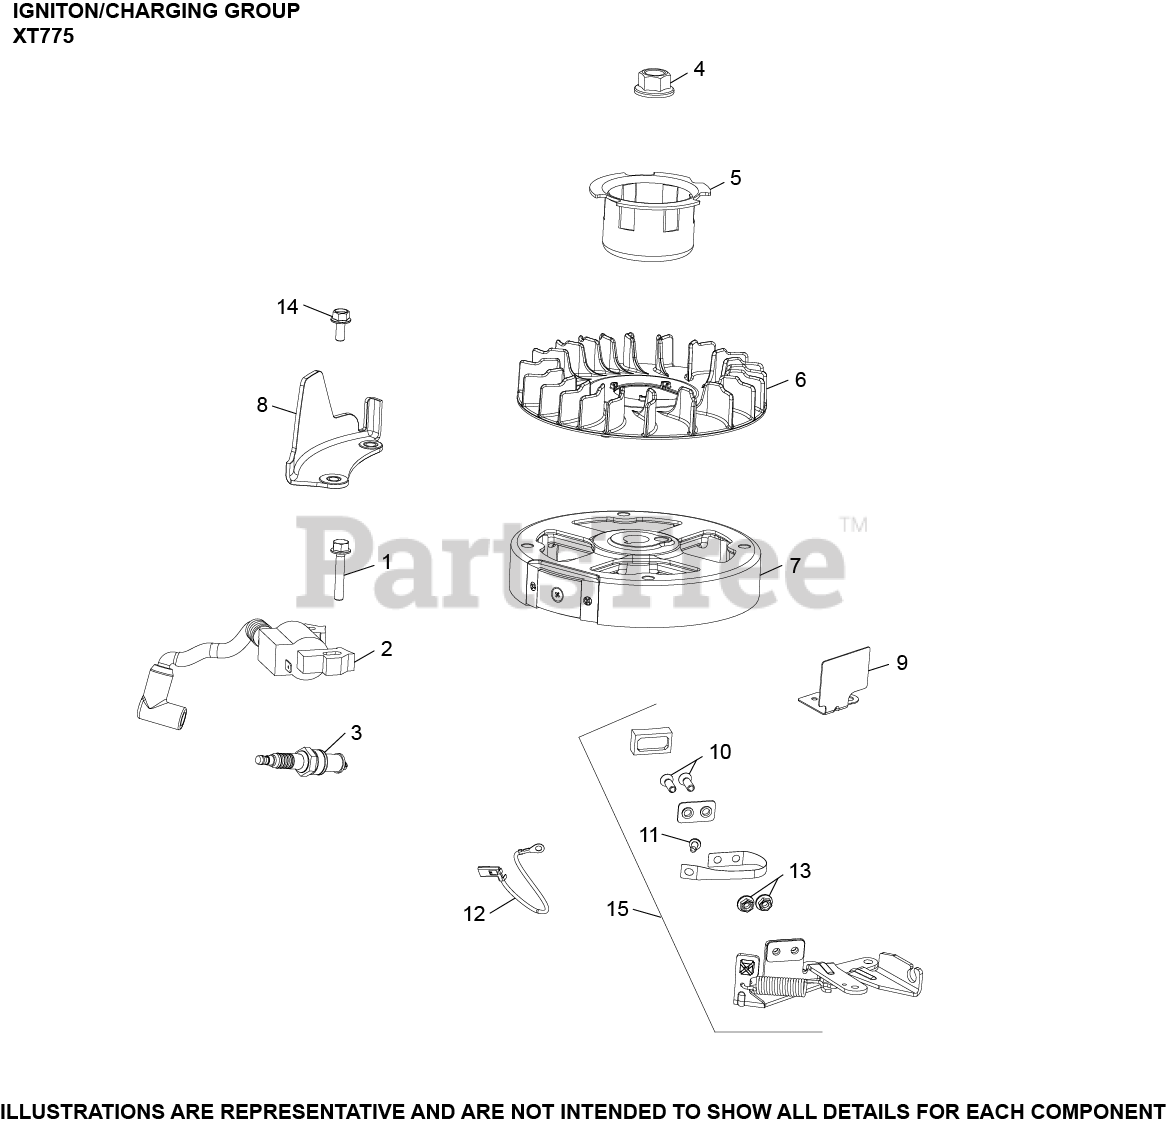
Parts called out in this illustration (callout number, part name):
1	SCREW, HEX FLANGE (M6)
2	MODULE IGNITION CAST IRON FLYWHEEL
3	PLUG, SPARK 12MM RFI
4	NUT, FLYWHEEL (W/SERRATIONS)
5	CUP, STARTER DRIVE
6	FAN, FLYWHEEL
7	FLYWHEEL (CAST IRON)
8	GUARD, FINGER
14	SCREW, HEX FLANGE (M6) (CKY)
